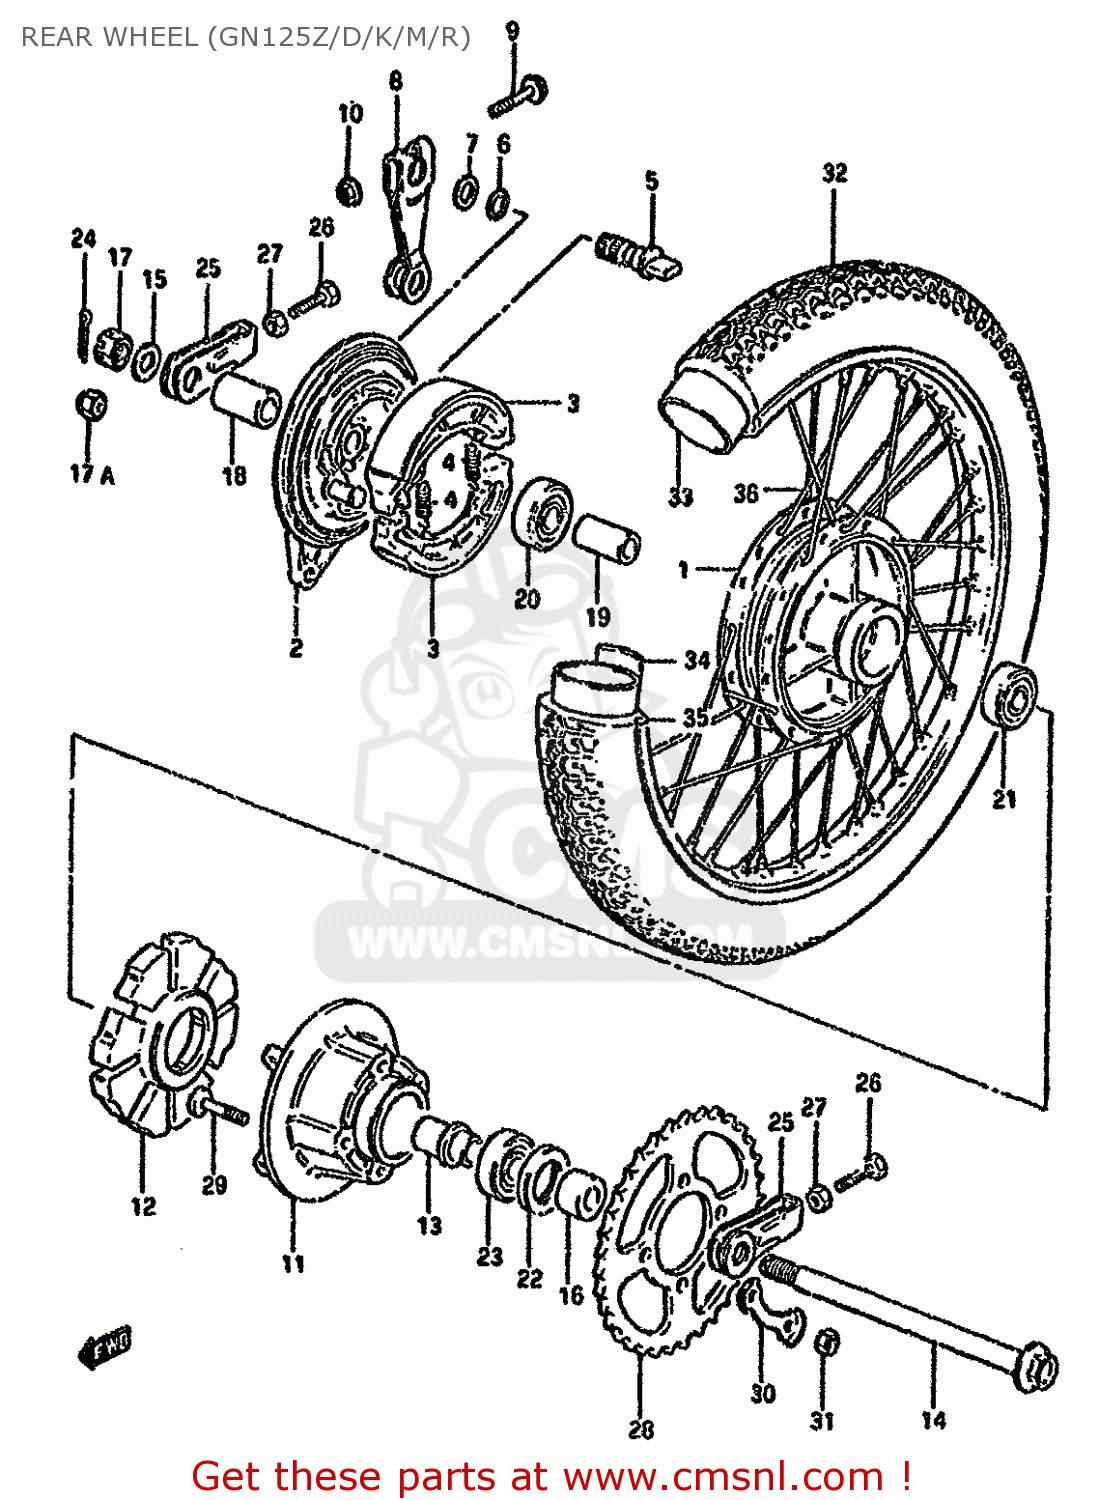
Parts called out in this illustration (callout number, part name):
1	HUB,RR
2	PANEL,RR BRAKE ANCHOR
3	SHOE,BRAKE
4	SPRING(L:34)
5	CAM,BRAKE
6	O-RING (D:2.4 ID:13.8)
7	WASHER (14.5X22X1.6)
8	LEVER,RR BRAKE CAM
9	BOLT
10	NUT
11	DRUM,RR SPROCKET MOUNTING
12	ABSORBER ASSY,HUB SHOCK
13	RETAINER,RR SPROCKET DRUM
14	AXLE,RR
15	WASHER
16	SPACER(15X28X19)
17	NUT
17A	NUT
18	SPACER(15.2X26X33)
19	SPACER(15.3X21.7X63)
20	BEARING
21	BEARING
22	SEAL,OIL(28X47X7)
23	BEARING(20X47X14)
24	COTTER PIN
25	ADJUSTER,CHAIN
26	BOLT
27	NUT
28	SPROCKET,REAR
29	BOLT
30	WASHER
31	NUT
32	TIRE
33	TUBE
34	PROTECTOR,INNER TUBE
35	RIM,RR WHEEL(185X16)
36	SPOKE ASSY,RR WHEEL
